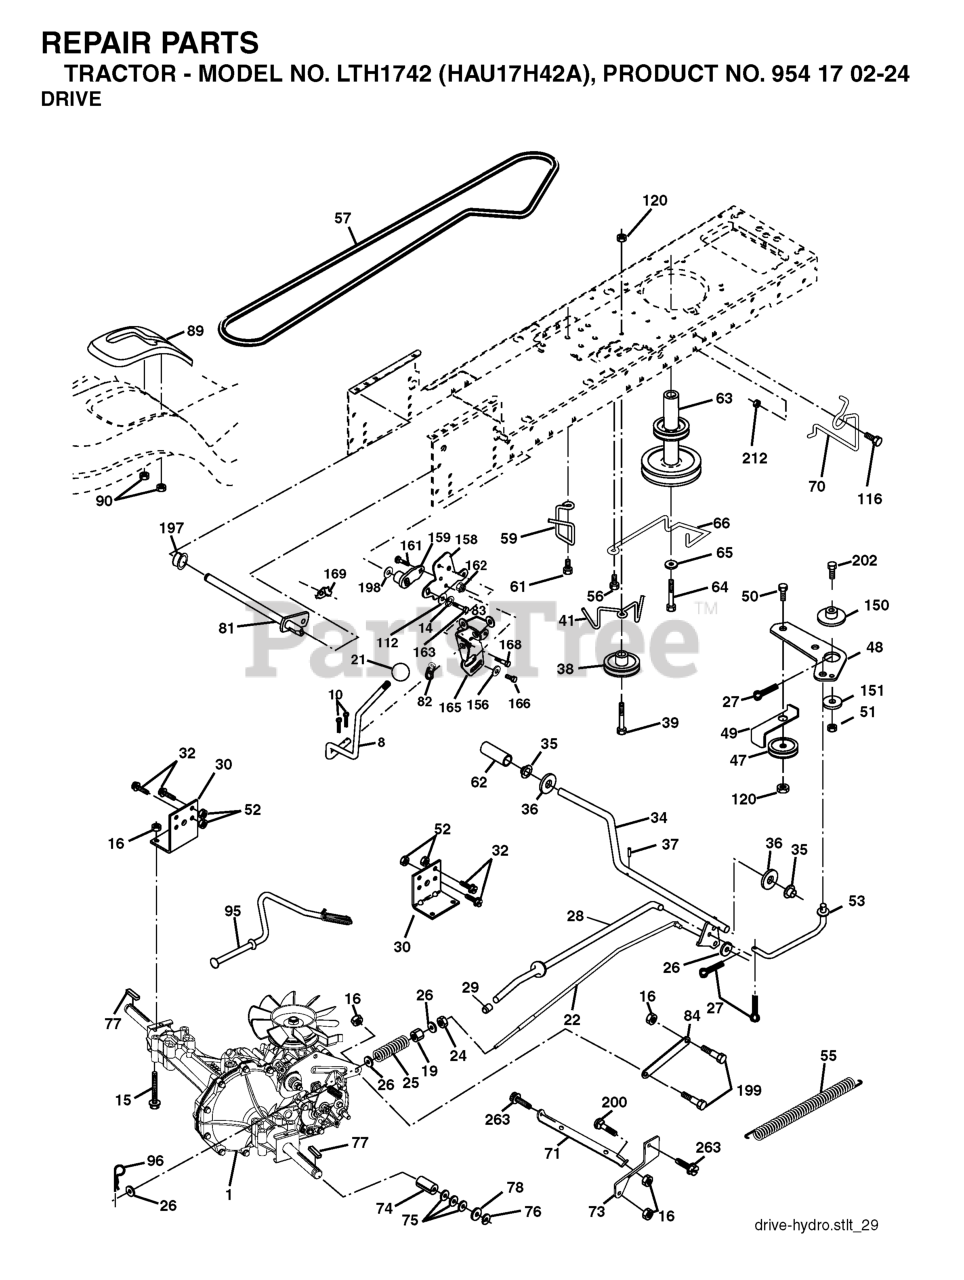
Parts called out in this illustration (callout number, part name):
8	ROD SHIFT FENDER ADJUST STLT
10	PIN COTTER
14	LOCKWASHER
15	BOLT HEX 5/16-18 GR 5
16	NUT.71038.31-18.HEX.NYLOCK
19	NUT
21	KNOB.DUCKHEAD.1/2
22	ROD BRAKE HYDRO
24	NUT
25	SPRING ROD LT
26	WASHER
27	COTTER PIN
28	ROD, PARKING BRAKE
29	PLUNGER CAP
30	BRKT, TRNSXLE MNT 20"
32	BOLT
34	SHAFT, FOOT PEDAL
35	BEARING.NYLON
37	DRIVE PIN
38	PULLEY IDLER COMPOSITE
41	KEEPER, BELT IDLER
47	IDLER PULLEY
48	BELLCRANK, CLUTCH
49	RETAIN BELT
50	BOLT.3/8-16X1.50
52	LOCKNUT
53	LINK, CLUTCH LT
55	SPRING, RETURN LT
56	SCREW.3/8-16
57	DRIVE BELT, LTH & YTH TRACTORS
59	KEEPER, BELT CENTER
61	SCREW 3/8-16X.875
62	COVER, PEDAL (1 2)
63	ENGINE PULLEY
64	BOLT HEX 7/16-20X4-1/4"
65	LOCKWASHER
66	KEEPER BELT ENGINE
70	KEEPER BELT ENG
71	STRAP TORQUE LH HYDRO
73	STRAP TORQUE RH HYDRO
74	SPACER AXLE
77	SQUARE KEY
81	SHAFT ASM CROSS TAPERED
82	SHIFT SPRING
83	WASHER
84	LINK TRANSAXLE
89	SHIFT CONSOLE
90	NUT.PUSH.3/16
95	CONTROL ASM. BYPASS HYDRO
96	RETAINER M
116	BOLT D
120	NUT LOCK FLG 3/8-16 UNC
150	SPACER, RETAINER
151	WASHER 12/32X2X10GA
156	WASHER.SRRTD.5/16
158	BRACKET
159	RB HUB.SHIFT
161	BOLT
162	NUT.CROWNLOCK.1/4
165	RP BRACKET
166	CAPSCREW.HXHD.FLG.5/16-18X.625
168	BOLT.SHOULDER.5/16-18X
169	PLATE.FASTENING.CROSS.SHAFT
197	NYLINER SNAP 5/8" ID
198	WASHER.NYL.7/8IDX.105"HYD CR
199	BOLT SHOULDER 5/16-18 UNC
212	NUT
263	SCREW, 3/8-16X3/4
